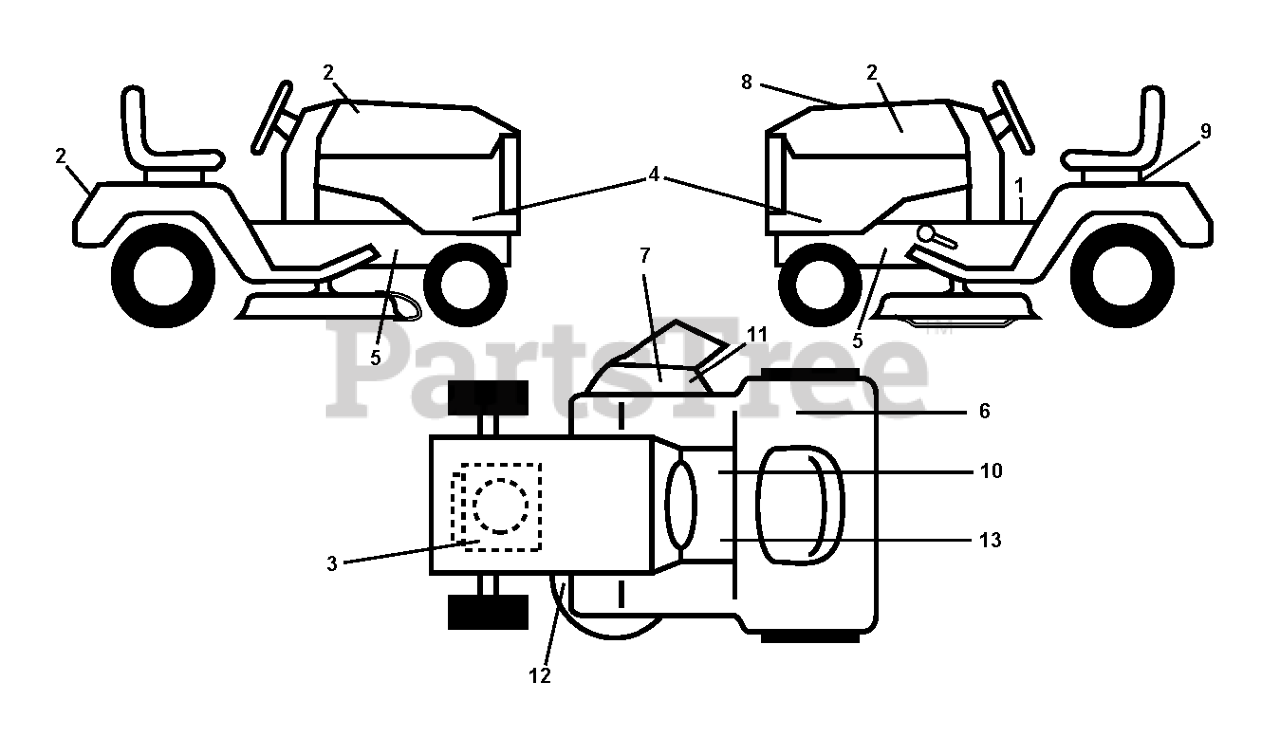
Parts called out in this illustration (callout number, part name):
1	LABEL
2	RP.DECAL.BADGE.170MM.TEXTLOGO
3	DECAL
4	DECAL SIDE PANEL
6	Decal, Fender 100 DB/CE
7	DECAL.INTERNATIONL.CUTFINGER
9	DECAL BTRY SYMBOLS
10	DECAL PARK BRAKE
11	DECAL, DEFLECT WARNING
12	DECAL.V-BELT.SCHEMATIC.36/38/9
13	DECAL
